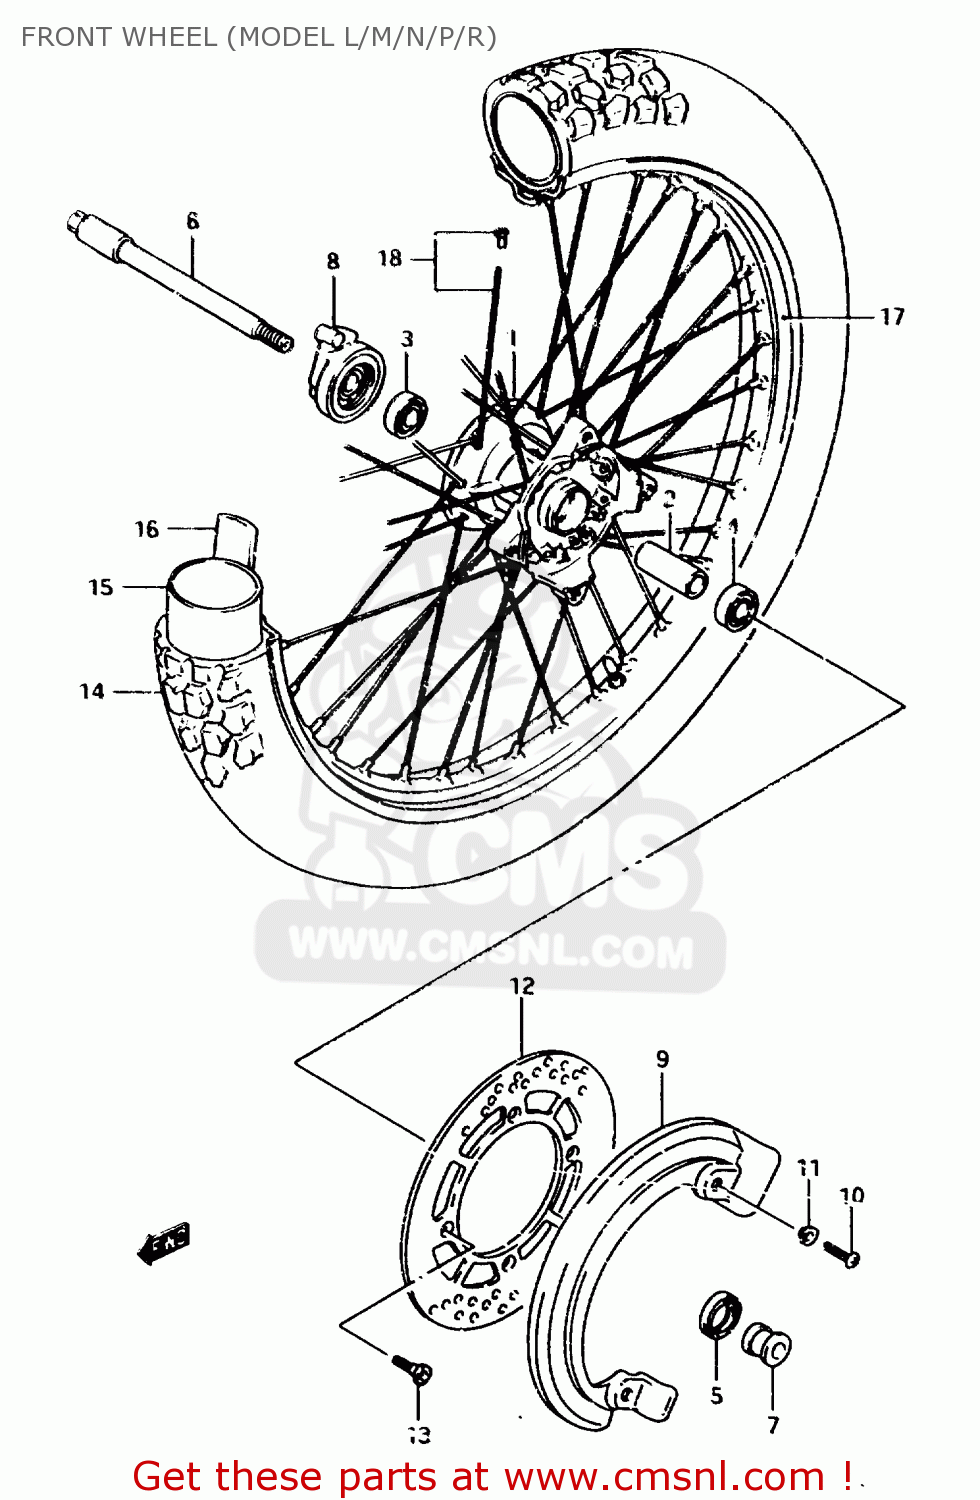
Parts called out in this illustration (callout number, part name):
1	HUB,FR WHEEL
2	SPACER,FR HUB BEARING
3	BEARING
4	BEARING
5	SEAL,OIL(22X35X5)
6	AXLE,FR
7	SPACER,FR AXLE,L
8	BOX ASSY,SPEEDOMETER GEAR
9	COVER,FR BRAKE DISC
10	SCREW
11	WASHER
12	DISC,FR BRAKE
13	BOLT,BRAKE DISC
14	TIRE, FRONT (2.75X21)
15	TUBE
16	PROTECTOR,WHEEL,INNER
17	RIM,FR WHEEL(1.60X21)
18	SPOKE SET
